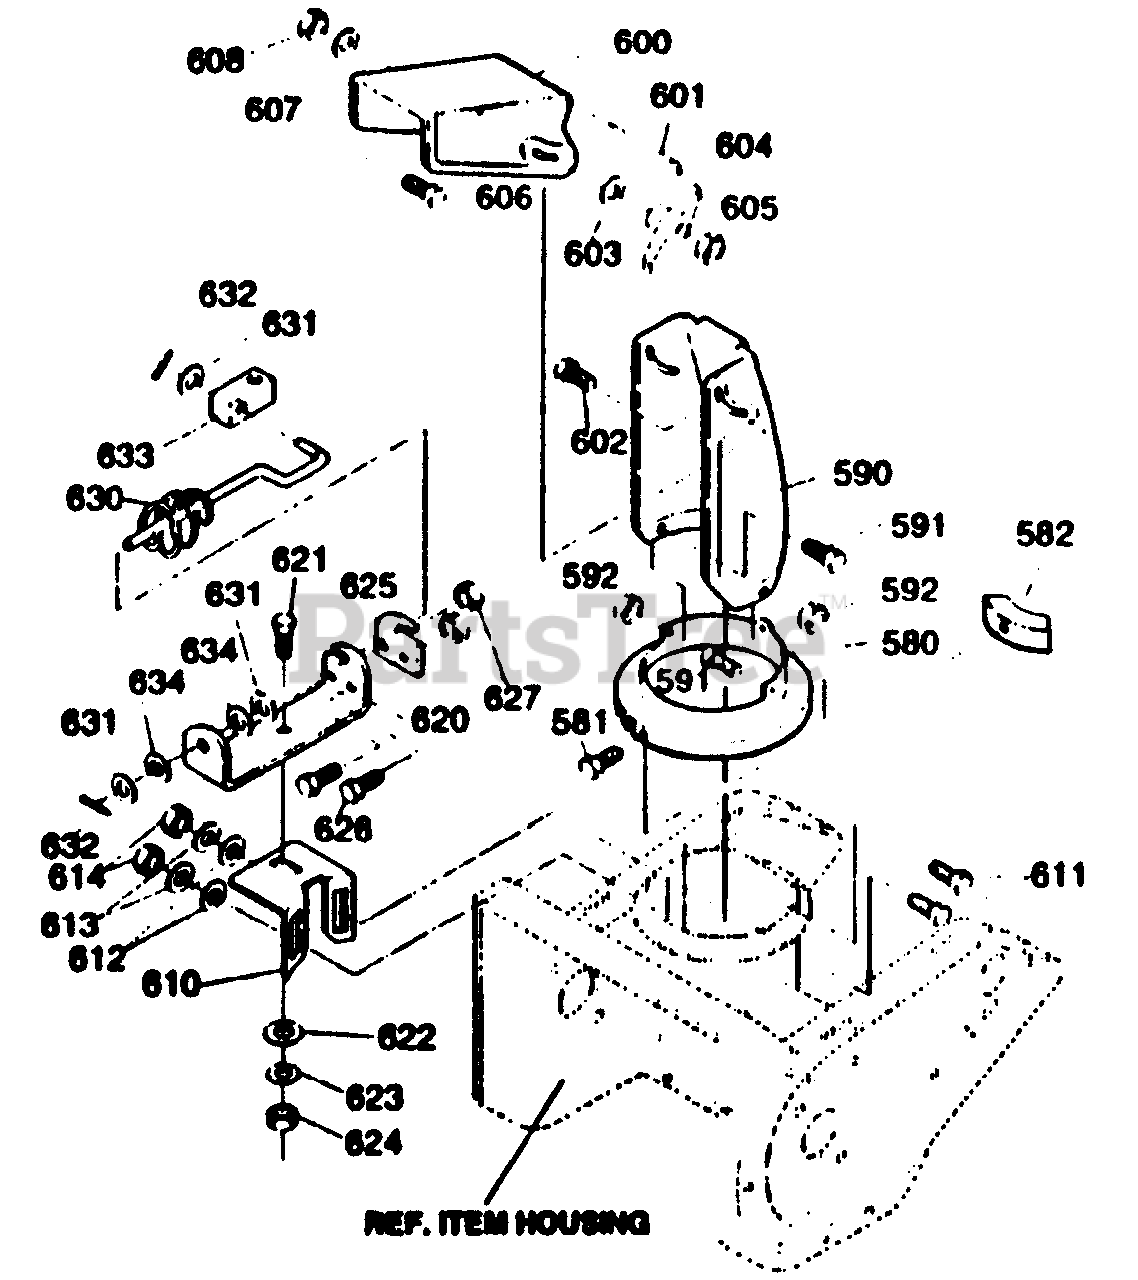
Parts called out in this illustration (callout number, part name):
580	RING, LOWER CHUTE
581	SCREW, 1/4-14X .63
582	CLIP, CHUTE RING
590	CHUTE, LOWER
591	SCREW, 1/4-20X .50
592	NUT, 1/4-20 WDFL MAC-LOCK
600	CHUTE, UPPER
601	WIRE, HINGE
602	BOLT, 5/16-18X1.25
603	WASHER, FLAT .344X .50X.065
604	KNOB, T
605	NUT, 5/16-18
606	SCREW, 5/16-18X .75
607	WASHER, FLAT .344X.69X.065
608	NUT, 5/16-18 REGHEXCTRLK
610	BRACKET, WORM ADJUST
611	BOLT, 5/16-18X .75
612	WASHER, FLAT .344X .69X.065
613	WASHER, HVSPTLK .328X.60X.09
614	NUT, 5/16-18 REGHEX
620	BRACKET, CHUTE ROD HOLDER
621	BOLT, 5/16-18X .75 CARR
622	WASHER, FLAT .344X .69X.065
623	WASHER, HVSPTLK .328X.60X.09
624	NUT, 5/16-18 REGHEX
625	PLATE, CHUTE ROD
626	SCREW, 1/4-20X .50
627	NUT, 1/4-20 REGHEXCTRLK
630	ROD, ASSY CHUTE LOWER
631	WASHER, FLAT .40 X .75X.025
632	PIN, COTTER .090 DIA X .75
633	BLOCK, PIVOT
634	WASHER, CURVED SPRING
